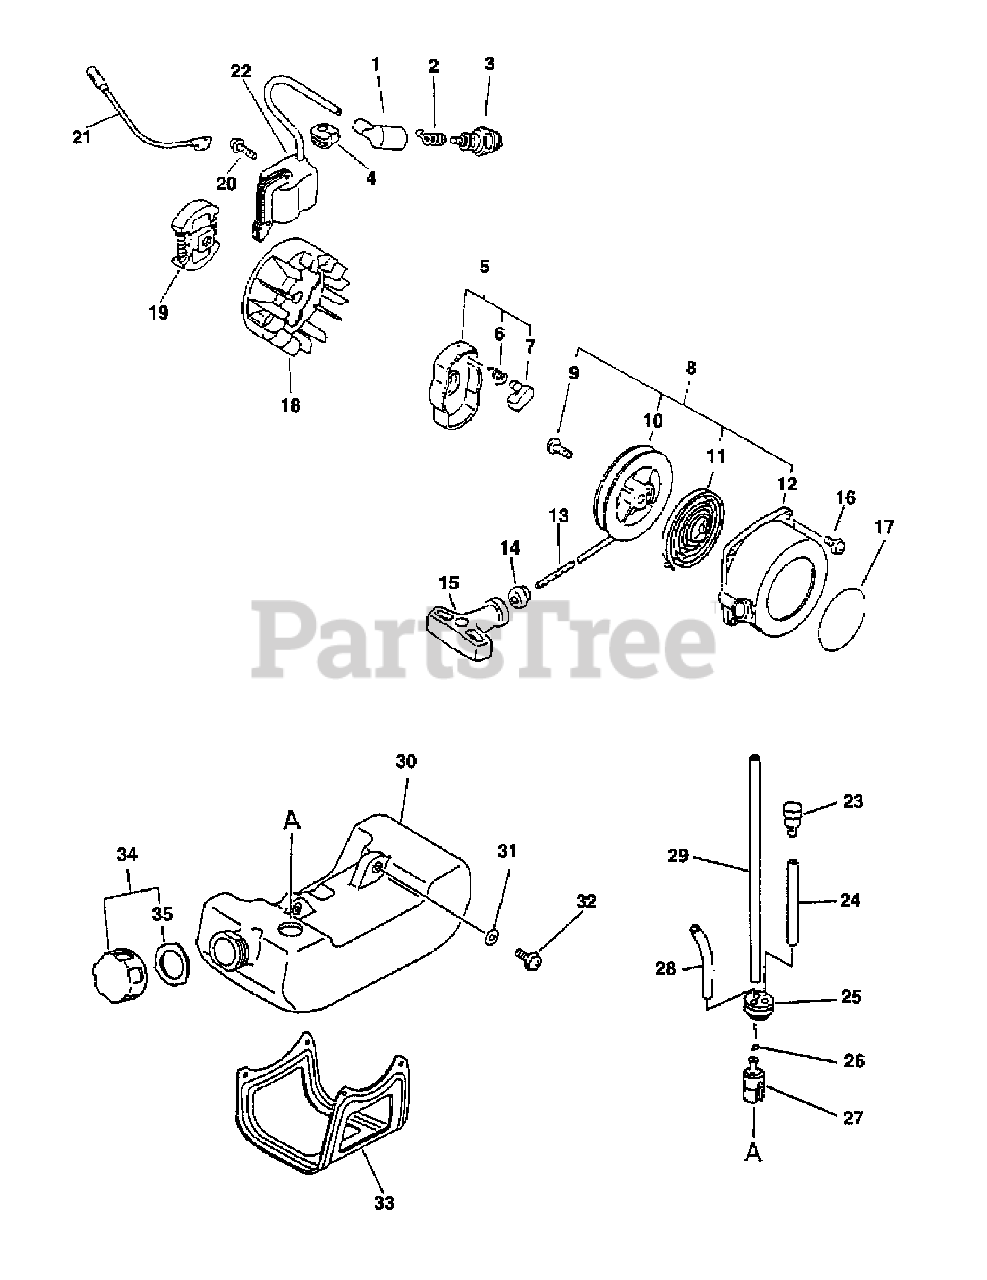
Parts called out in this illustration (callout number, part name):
1	CAP, SPARK PLUG
2	TERMINAL, SPARK PLUG
3	SPARK PLUG - BPM-7Y
3	SPARK PLUG - BPMR7A
5	PAWL ASSY, STARTER
6	SPRING, RETURN
7	PAWL, STARTER - BLACK
8	STARTER ASSY, RECOIL
9	SCREW
10	REEL, ROPE
11	SPRING, RECOIL
12	CASE, RECOIL STARTER
13	ROPE, STARTER 3.0×1000
14	GUIDE, ROPE
15	GRIP, STARTER
16	BOLT 4×16
17	LABEL, ECHO
18	FLYWHEEL
19	CLUTCH ASSY
20	SCREW 4×22
21	LEAD
22	COIL, IGNITION
23	VENT ASSY
24	PIPE, FUEL 3x-5x-70 BLACK
25	GROMMET, FUEL
26	CLIP 6 MM
27	FILTER, FUEL
28	PIPE, FUEL RETURN 3×6×90 MM CLEAR
29	PIPE, FUEL 3x-5x-180
30	TANK, FUEL
31	WASHER 5.5×12×0.8
32	SCREW 5×16
33	GUARD, FUEL TANK
34	CAP ASSY, FUEL
35	GASKET, FUEL CAP
